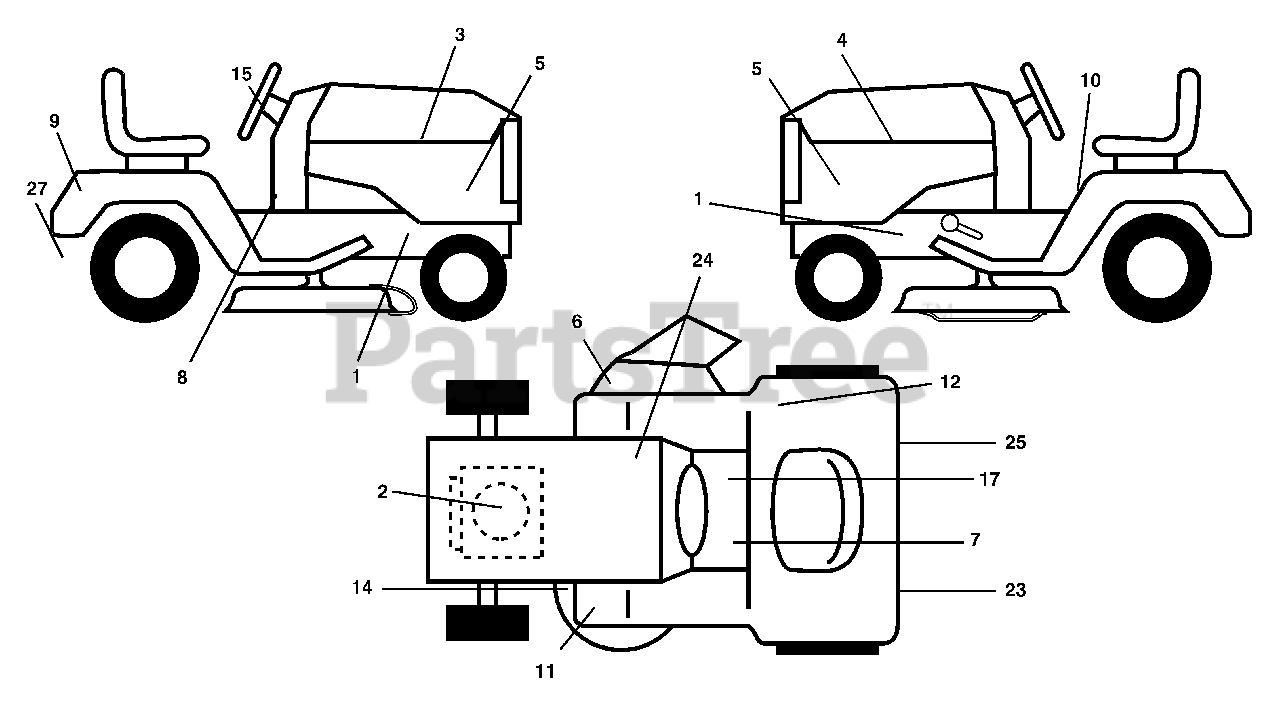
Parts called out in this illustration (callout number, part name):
2	Decal, Engine
3	Decal, Hood, RH
4	Decal, Hood, LH
5	Decal, Side Panel
6	Decal, Warning
8	Decal, Dash
9	Decal, Fender
10	Decal, Read Owner's Manual Syms.
11	Decal, Foot Rest
14	Decal, V-Belt Schematic
15	Decal, Ins. Strg Whl
17	Decal, Saddle Brake Parking
23	Reflector, Taillight LH
24	Decal, Btry Dngr/Psn
25	Reflector Taillight RH
27	Decal, Drawbar
